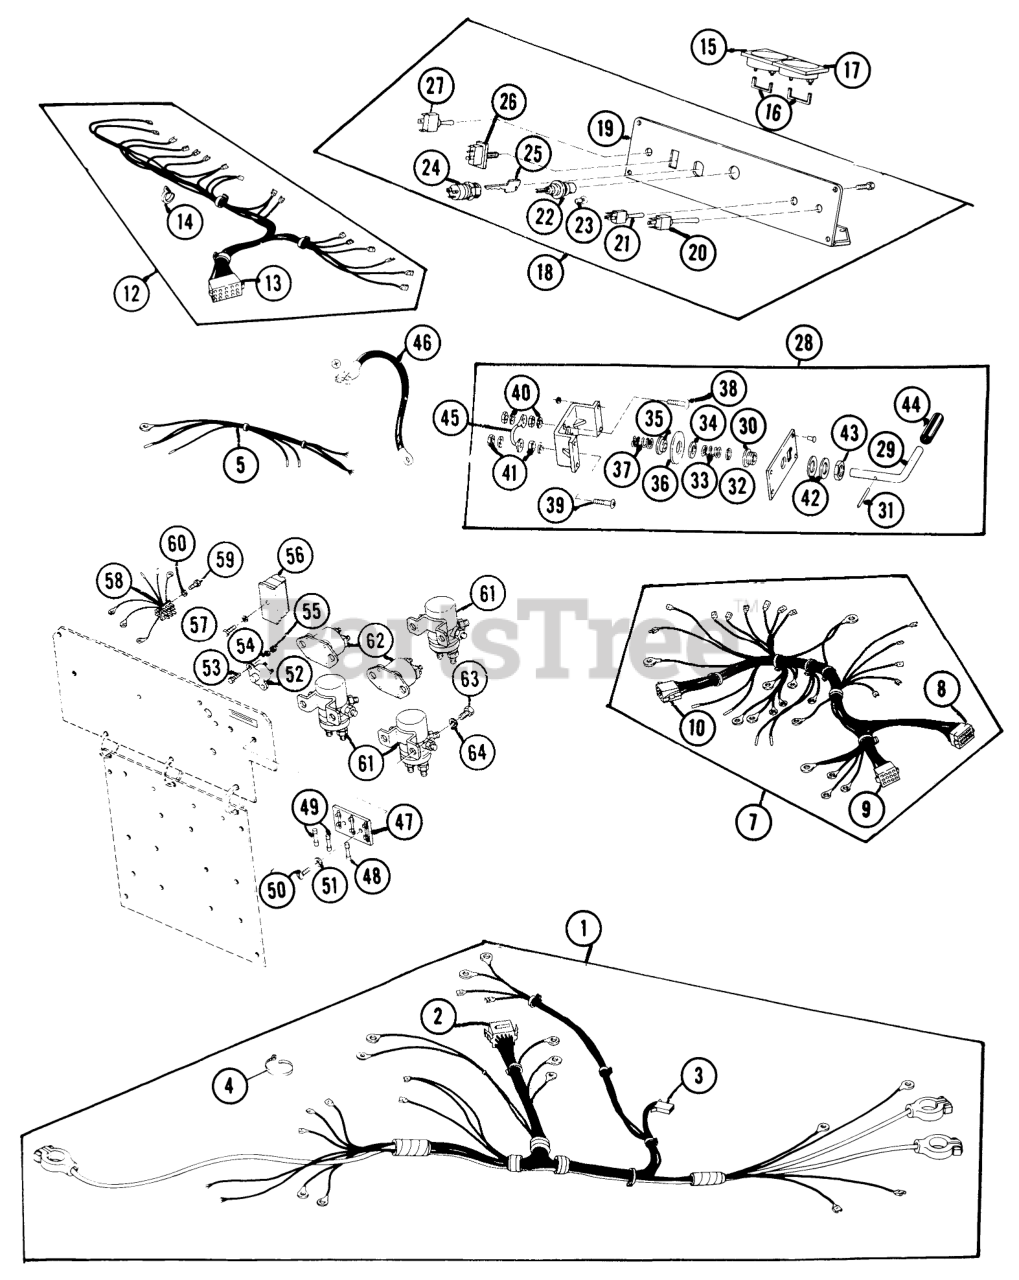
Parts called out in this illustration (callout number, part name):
16	Bracket
30	Bushing
36	Contact Disc
41	Nut, 1/4-20
45	Fusesble Link
50	Thd. Rolling Screw 6-32 x 1/2
52	Circuit Breaker
53	Screw, Machine, #10-32 x 3/4
57	Screw, Hex Machine #8-32 x 3/8
